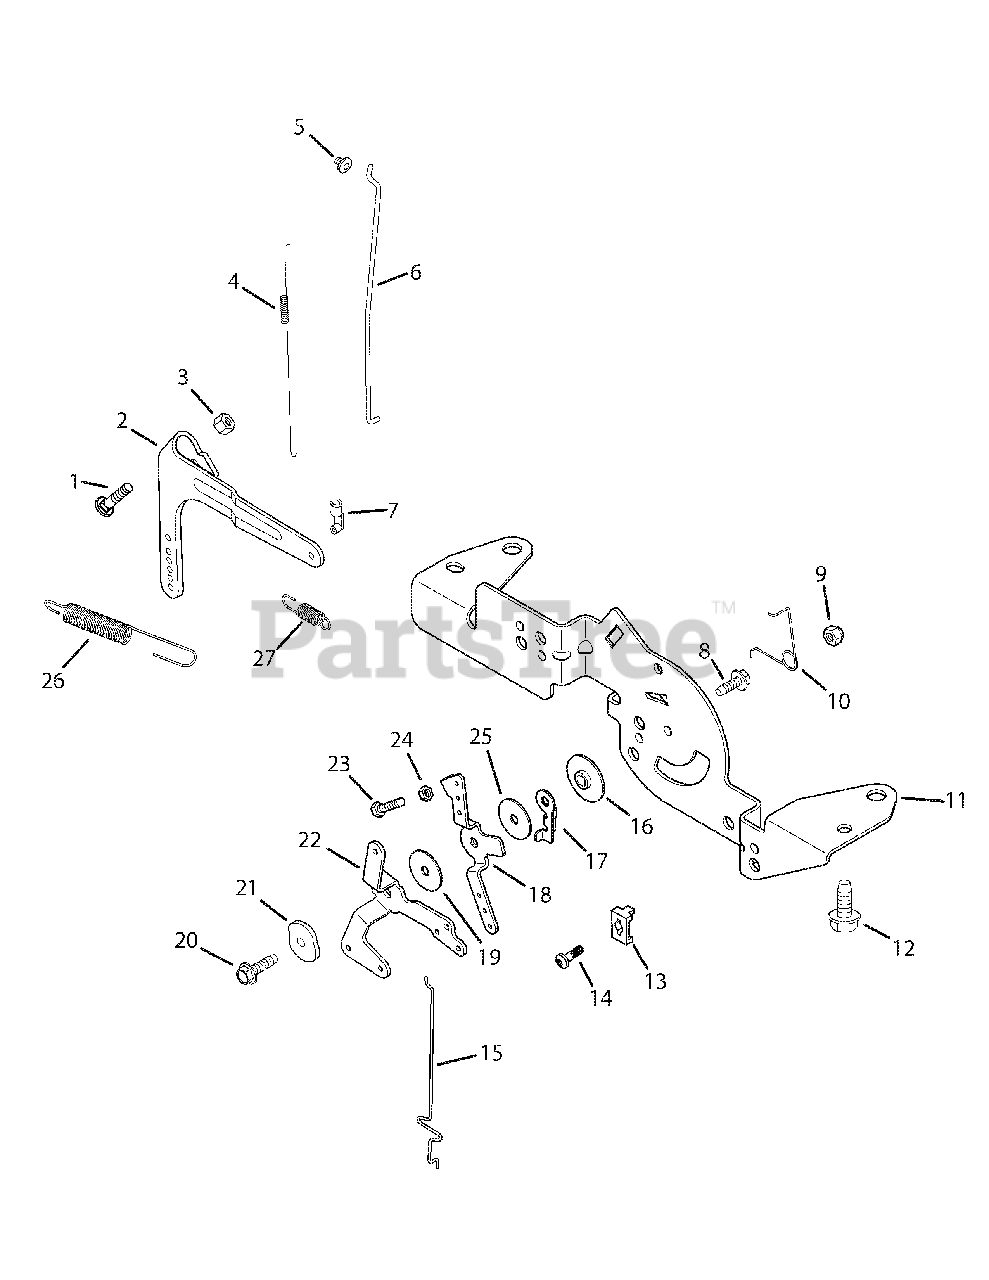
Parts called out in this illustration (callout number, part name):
1	Bolt, round hd square neck
2	Lever, governor
3	Nut, hex. flange M6x1.0
4	Spring, linkage
5	Bushing, linkage retaining
6	Linkage, throttle
7	Bushing, throttle linkage
8	Screw, hex. flange, M5x0.8x16
9	Nut, hex. lock M5x0.8
10	Spring, choke return
11	Bracket, control
12	Screw, hx. flange M6x1.0x16
13	Clamp, dual conduit
14	Screw, thread forming
15	Linkage, choke
16	Spacer, control assembly
17	Lever, throttle actuator
18	Lever, throttle control
19	Washer, plain 5.5 mm
20	Screw, hx. flange M5x0.8x20
21	Washer, spring 1/4"
22	Lever, choke
23	Screw, hex. head cap M4x0.7x25
24	Nut, hex. M4x0.7
25	Washer, plain
26	Spring, governor
27	Spring, governor
